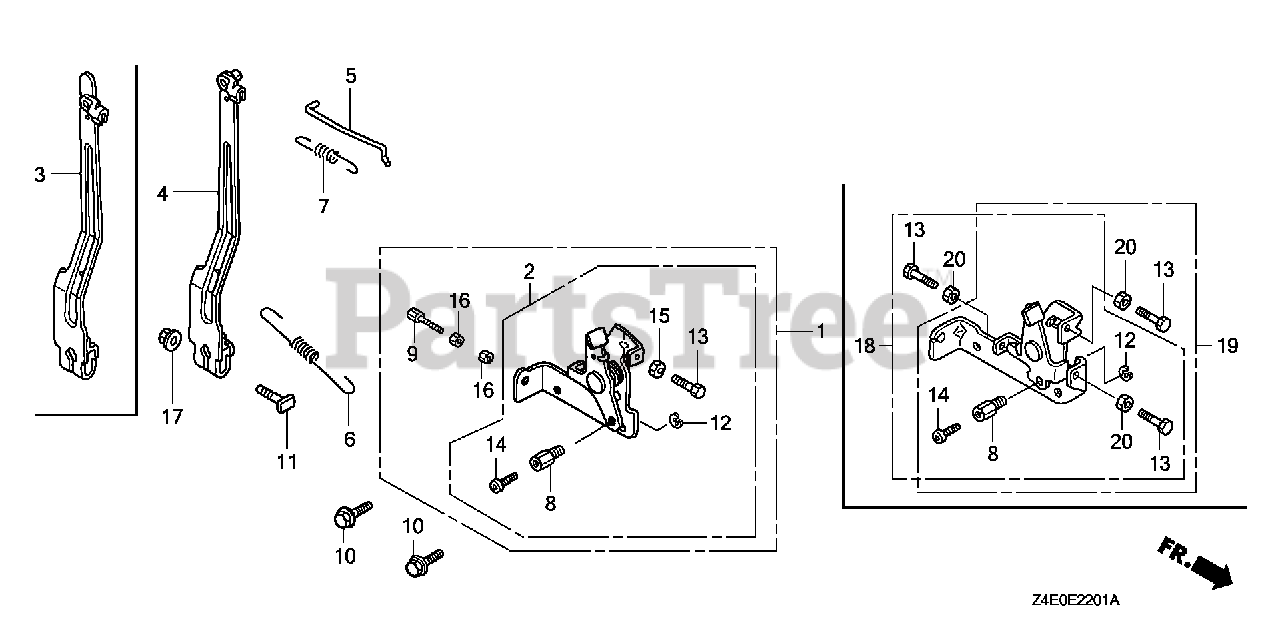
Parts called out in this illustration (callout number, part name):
3	ARM, GOVERNOR
5	ROD, GOVERNOR
6	SPRING, GOVERNOR
7	SPRING, THROTTLE RETURN
8	HOLDER, WIRE
10	BOLT, FLANGE (6X14) (CT200)
11	BOLT, GOVERNOR ARM
12	CIRCLIP (5MM)
13	BOLT, HEX. (5X20)
14	SCREW, PAN (4X6)
17	NUT, FLANGE (6MM)
19	CONTROL ASSY.
20	NUT, HEX. (5MM)
